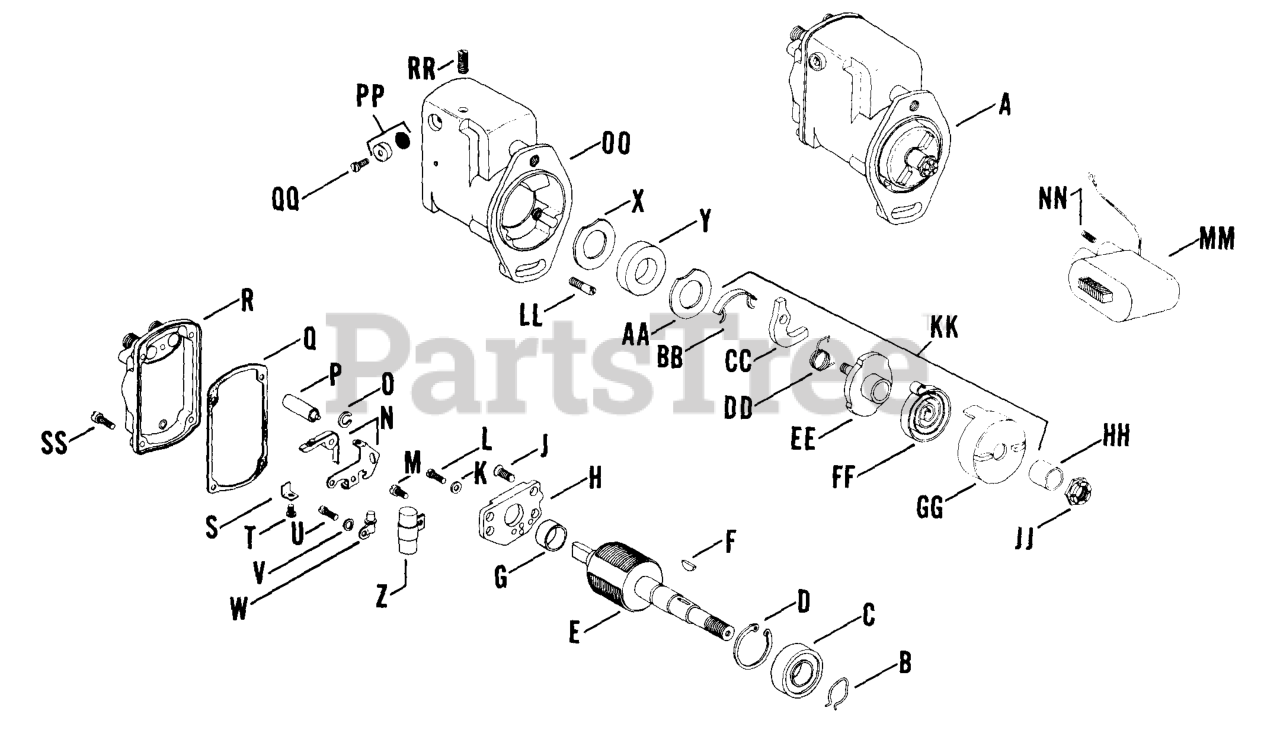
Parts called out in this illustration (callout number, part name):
C	Bearing, drive end
G	Bearing, cam end
L	Screw, support #8 - 32 x 3/8
M	SCREW - DISCONTINUED
O	Ring, snap - fulcrum pin
R	CAP - DISCONTINUED
S	Spring, switch
T	Screw, terminal #6 - 32 x 3/8
U	SCREW - USE X-51-13
W	Wick, cam
DD	SPRING - DISCONTINUED
LL	Pin, pawl stop
NN	Spring, coil lead
OO	Housing
QQ	Screw, cover #6 - 32 x 1/4
SS	SCREW - USE X-50-3
